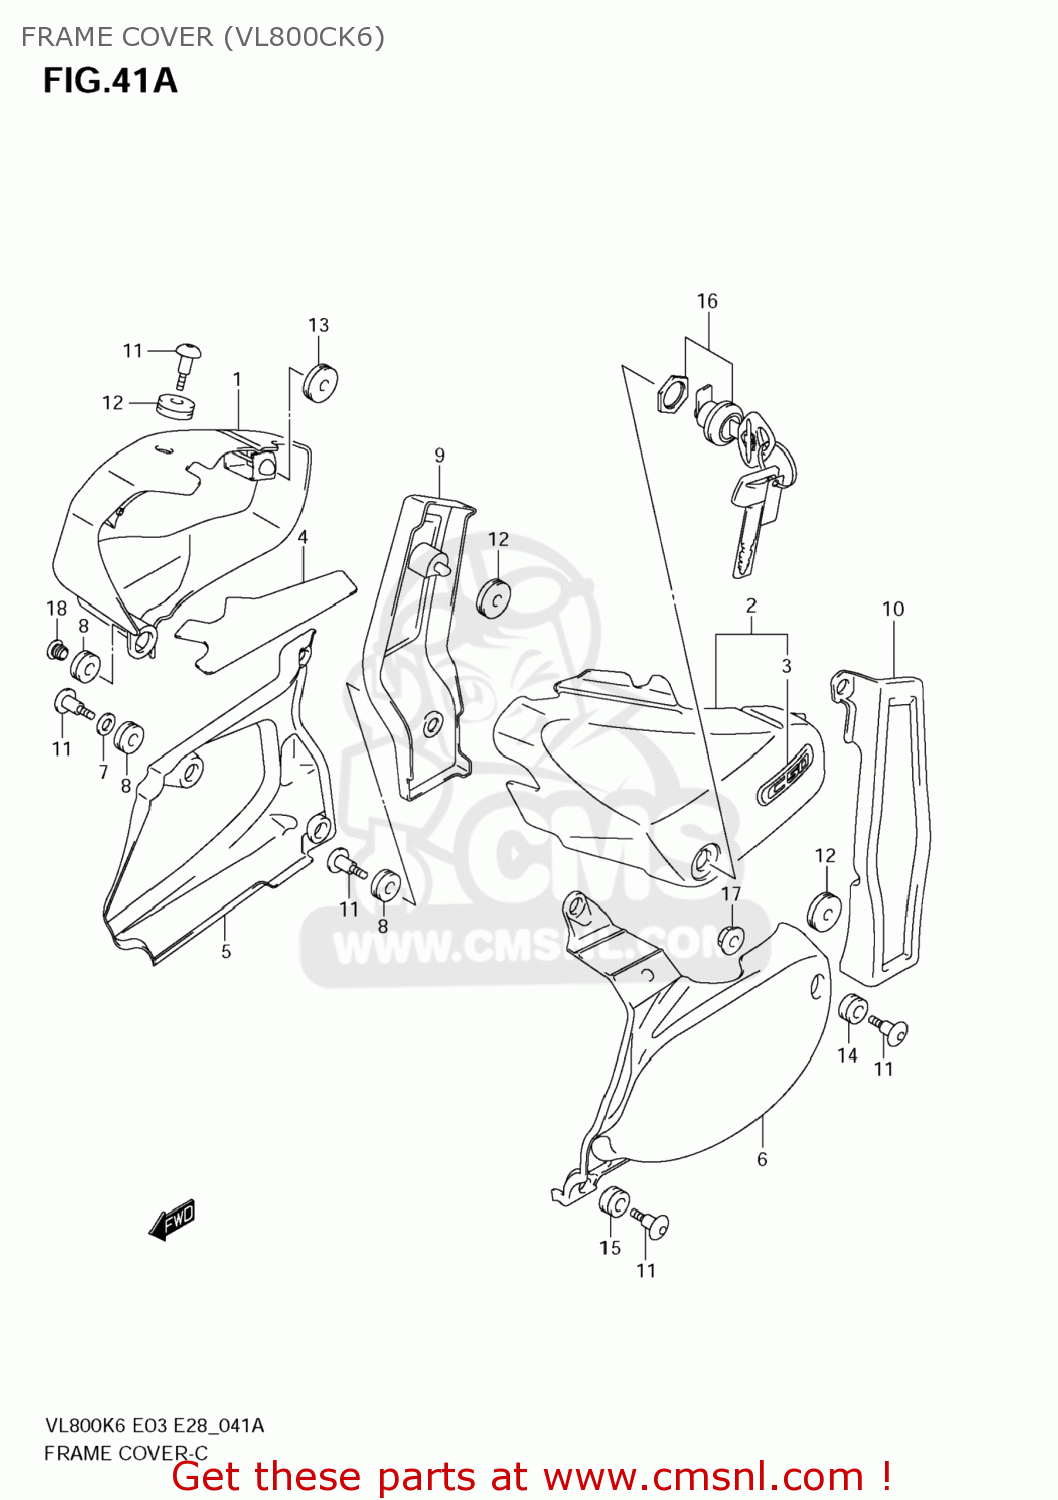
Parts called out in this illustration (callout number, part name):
1	COVER,SIDE,R(WHITE)
2	COVER,SIDE,L(WHITE)
3	EMBLEM,C50
4	SHIELD,FRAME COVER
5	COVER,SIDE LWR,R
6	COVER,SIDE LWR,L
7	WASHER(10.5X20X2.3)
8	CUSHION
9	COVER,SIDE RR,R
10	COVER,SIDE RR,L
11	SCREW(6X20)
12	CUSHION
13	CUSHION
14	CUSHION
15	CUSHION
16	LOCK SET,COVER
17	NUT
18	CAP(OD:14)
